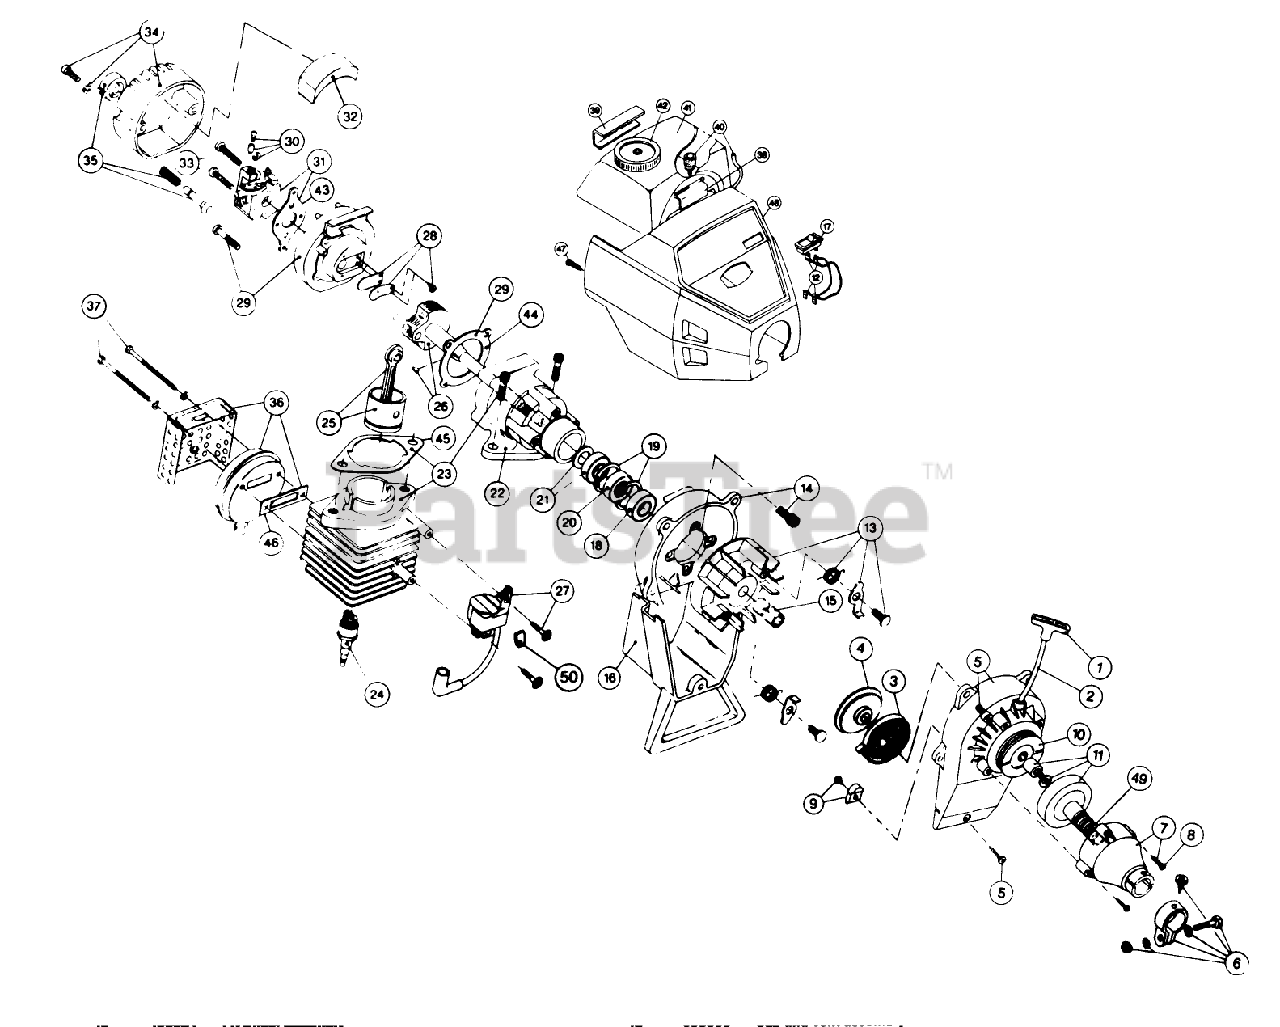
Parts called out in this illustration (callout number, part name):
6	CLAMP ASM - UPPER
14	SHROUD ASM
18	OUTER BEARING
21	INNER BEARING ASM
24	SPARK PLUG
30	THROTTLE ADJ ASM
37	MUFFLER MOUNTING BOLTS
38	Front mounting pad
39	REAR MOUNTING PAD
40	FUEL LINE ASM
43	CARB.GASKET
49	COMPRESSION SPRING
